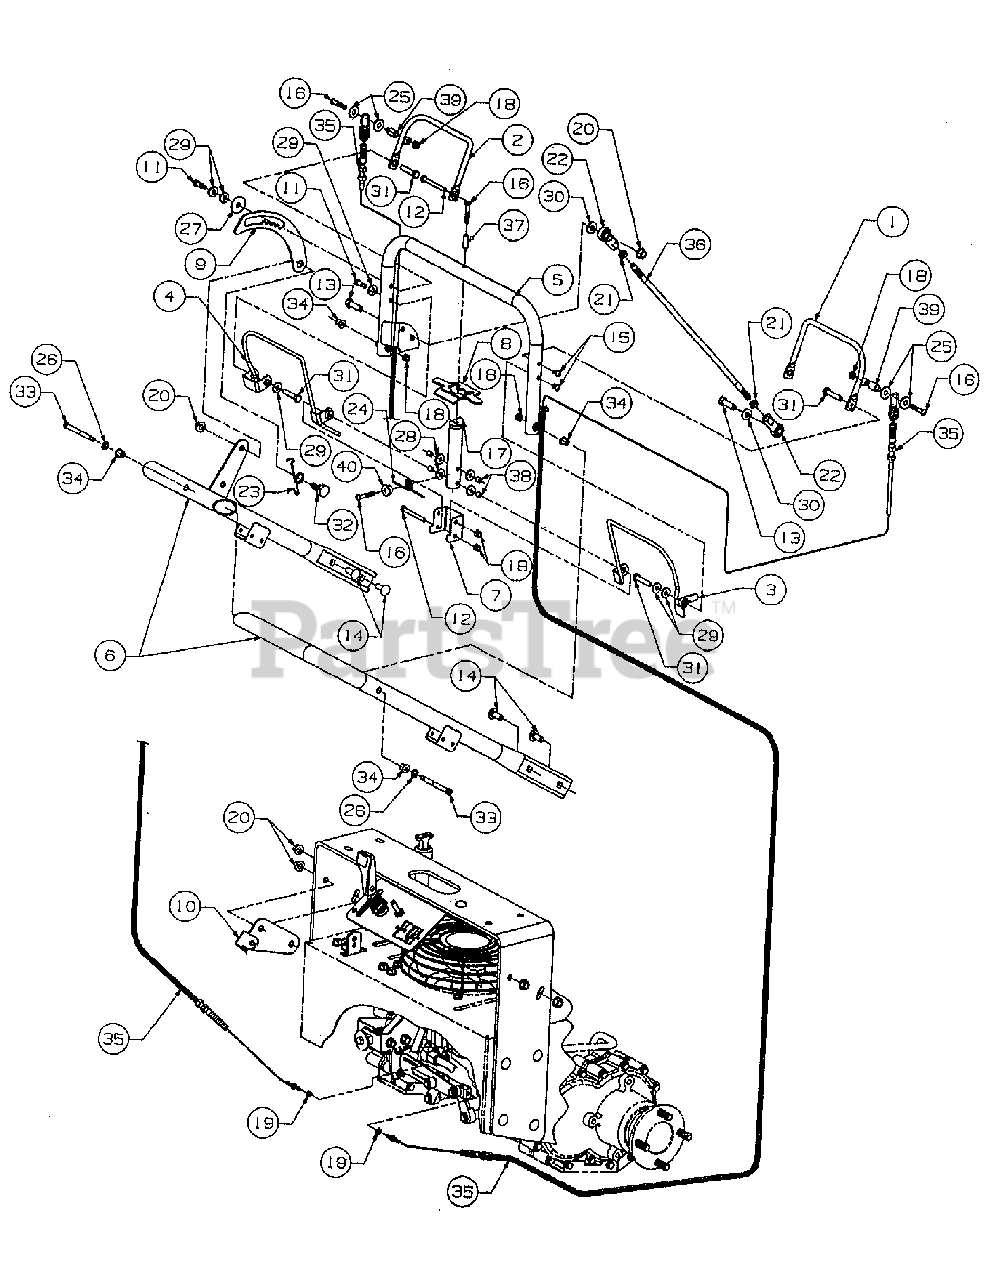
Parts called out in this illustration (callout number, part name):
1	Lever w/ Bushings, RH Brake
2	Lever w/ Bushings, LH Brake
3	Lever w/ Bushings, Operator-Present
4	Lever w/ Bushings & Graphic
4	Graphic, Speed Set
5	Bar w/ Graphics, Traction Control
5	Graphic, F-N-R
5	Graphic, Traction Control
8	Latch w/ Graphic, Park Brake
8	Graphic, Park Brake
9	Plate, Speed Set
10	Bracket, Cable Mounting
11	Screw, Socket Hd Shoulder
12	Screw, Hex Cap, 1/4-20 x 2.50 Gr 5
13	Screw, Hex Cap, 3/8-16 x 1.25
14	Bolt, Carriage, 3/8-16 x 1.0 Gr 5
15	Screw, Button Hd, 1/4-20 x .50
16	Screw, Button Hd, 1/4-20 x 1.50
17	Post, Parking Brake
18	Nut, Hex Toplock, 1/4-20
19	Nut, Hex #10-32
20	Nut, Hex Flanged Lock, 3/8-16
21	Nut, Hex Jam, 3/8-24 Gr 5
22	Rod End, Spherical, 3/8-24
23	Spring, Torsion
24	Spring, Torsion
25	Washer, Flat, .344 x .88 x .063 Thk
26	Washer, Flat, .344 x .62 x .03 Thk
27	Washer, Flat, .32 x 1.25 x .06 Thk
28	Washer, Flat, .281 x .750 x .119 Thk
29	Washer, Flat, .344 x .750 x .120 Thk
30	Washer, Flat, .407 x .812 x .135 HDN
31	Bolt, Shoulder
32	Bolt, Stepped Shoulder
33	Bolt, Shoulder
34	Bushing, Fliplock
35	Cable, Brake Clutch
36	Rod, F/R Control
37	Spacer, 5/16 OD x 1/4 ID x .94
38	Spacer, 5/16 OD x 1/4 ID x .375
39	Spacer, Cable
40	Spacer, Spring
